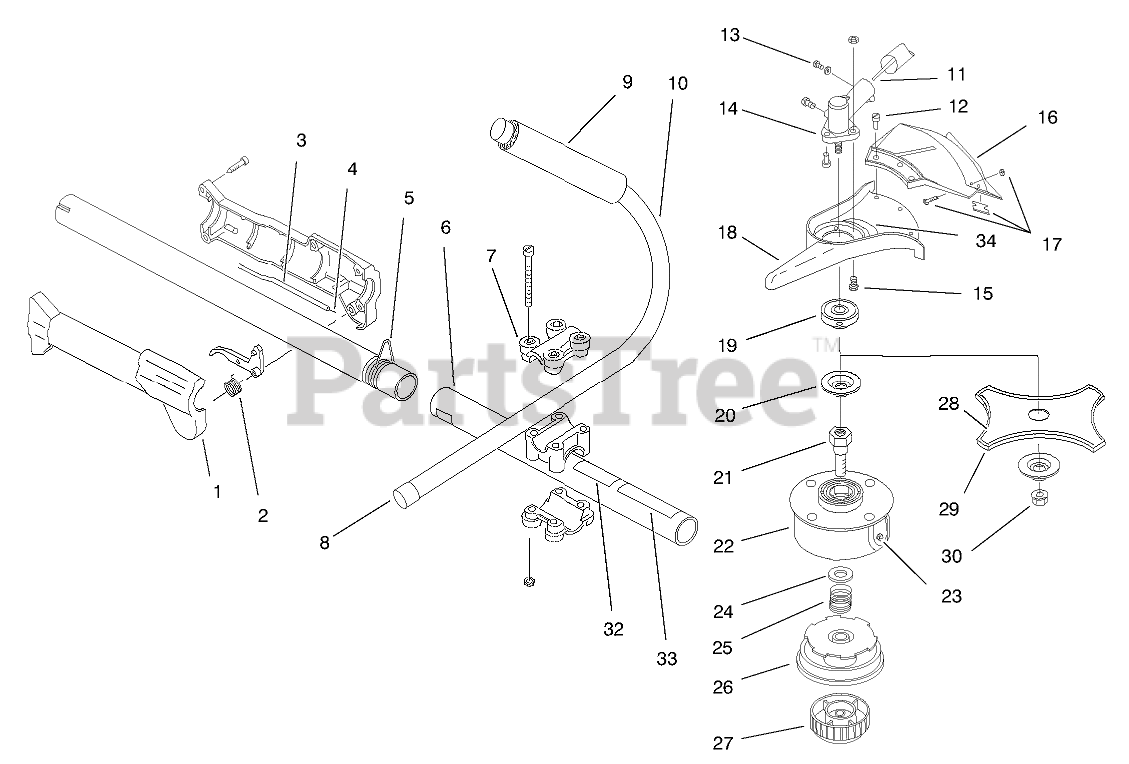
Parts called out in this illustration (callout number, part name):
1	ASM-THROTTLE HSG/TRIGGER
2	THROTTLE TRIGGER SPRING
3	Throttle Cable Housing
4	WIRE-THROTTLE
5	Clip-Shoulder Strap
6	DRIVE SHAFT HSG ASM
7	HANDLE BRACKET ASM
8	TUBE CLOSURE
9	HANDLE NITRILE GRIP
10	J-Handle Asm. (Incl. Ref. #8-9)
11	SHAFT - FLEXIBLE DRIVE
12	SCREWS - GUARD MOUNTING
13	MTG HDW&PLUG SET
14	Gear Box Asm. (Incl. Ref. #13, 19, 20, 30)
15	GUARD MNTG SCREW ASM
16	Guard and Blade Asm. (Incl. Ref. #17)
17	BLADE ASM
18	GUARD MOUNT
19	BLADE DRIVER
20	Blade Retaining Washer
21	SPOOL SHAFT
22	Outer Spool & Eyelet Asm.
23	EYELET
24	RETAINER ( 10 PACK)
25	SPRING
26	INNER REEL
27	BUMP HEAD KNOB ASSEMBLY
28	Blade
29	BLADE SAFETY GUARD
30	BLADE RETAINER NUT
32	Decal-Safety Symbol
33	DECAL - SAFETY
34	DECAL - WARNING
